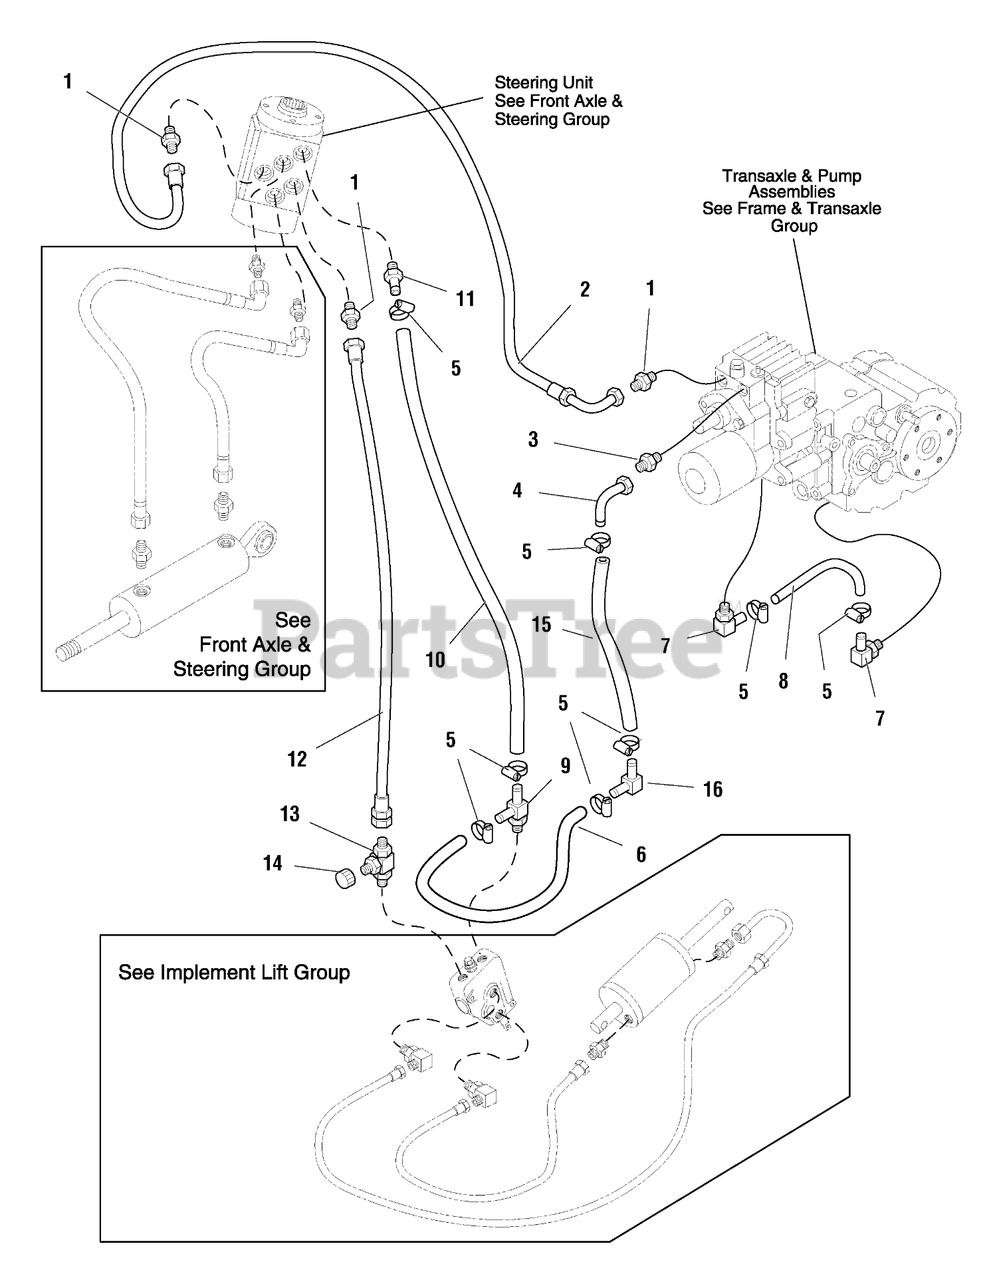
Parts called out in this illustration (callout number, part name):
1	FITTING, Male, Straight
2	HOSE, Pump to Steer
3	FITTING, Hydraulic
5	CLAMP, Hose
6	HOSE, Return
7	FITTING, Hydraulic, 7/8-14
8	HOSE, Pre Formed
9	FITTING, Tube
10	HOSE ASSEMBLY, Return (Steer/Lift)
11	FITTING, Male
12	HOSE ASSEMBLY, Steer to Lift
13	FITTING, Tube Tee
15	HOSE, Hydraulic 1/2"
16	FITTING, Hose Elbow 90 Degree 1/2"
